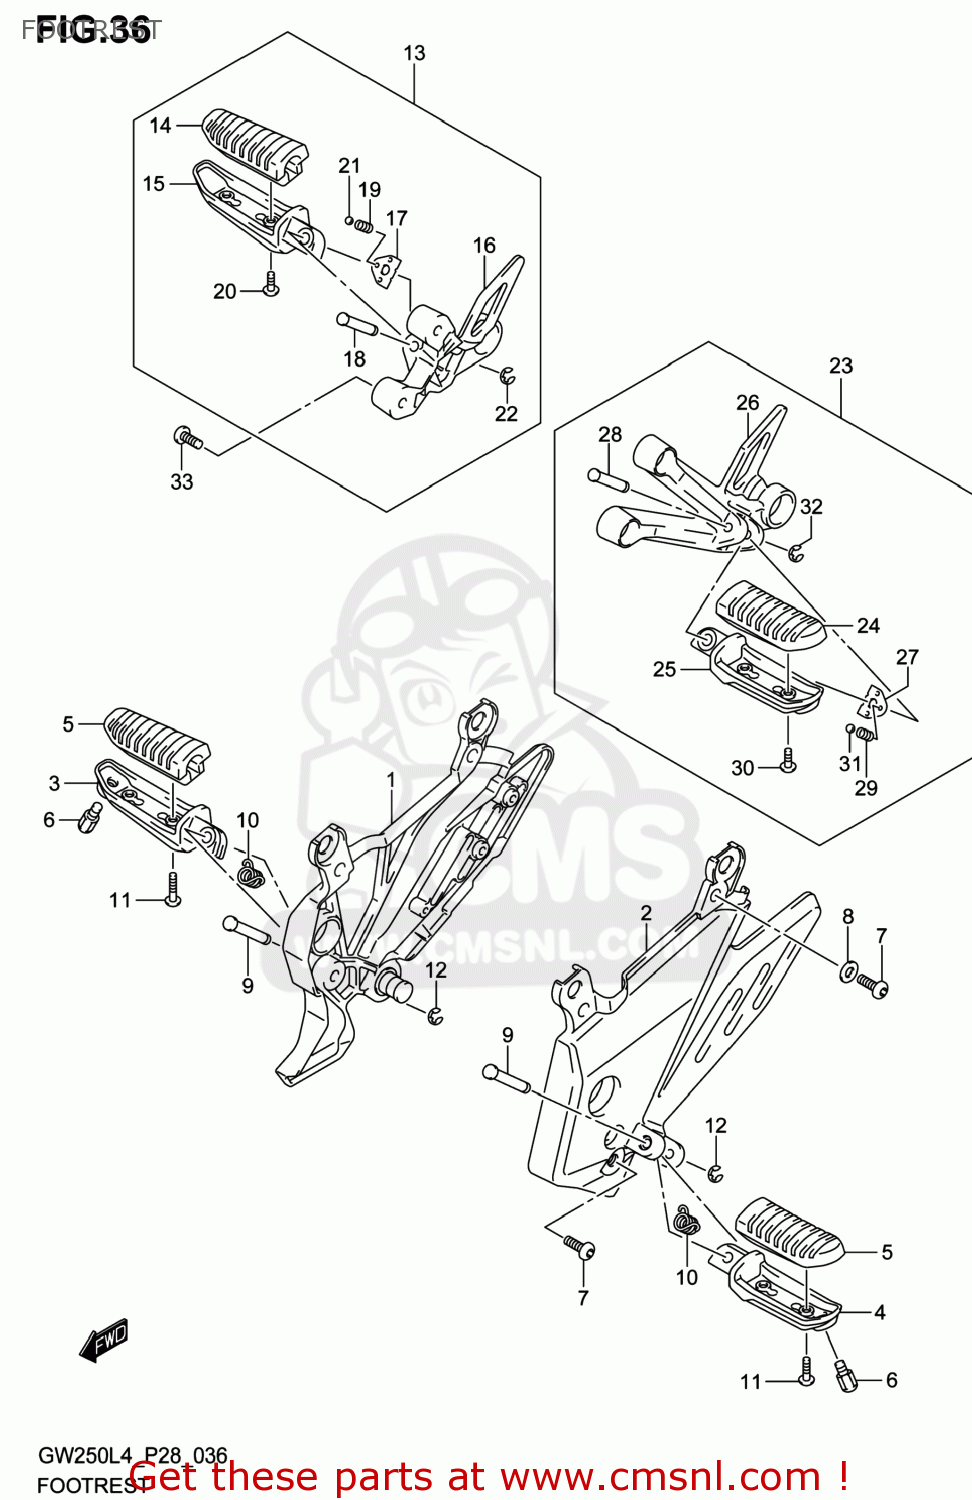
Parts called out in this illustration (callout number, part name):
1	BRACKET,FOOTREST,R
2	BRACKET,FOOTREST,L
3	BAR,FR FOOTREST,R
4	BAR,FR FOOTREST,L
5	RUBBER,FOOTREST
6	BOLT,BANK SENSOR
7	BOLT(8X20)
8	WASHER(9X19X1.0)
9	PIN
10	SPRING
11	SCREW
12	E RING
13	FOOTREST ASSY,PILLION,R
14	RUBBER,FOOTREST
15	BAR,PILLION FOOTREST,R
16	BRACKET,PILLION FOOTREST,R
17	PLATE,PILLION FOOTREST
18	PIN
19	SPRING
20	SCREW
21	BALL
22	E RING
23	FOOTREST ASSY,PILLION,L
24	RUBBER,FOOTREST
25	BAR,PILLION FOOTREST,L
26	BRACKET,PILLION FOOTREST,L
27	PLATE,PILLION FOOTREST
28	PIN
29	SPRING
30	SCREW
31	BALL
32	E RING
33	BOLT(8X23)
